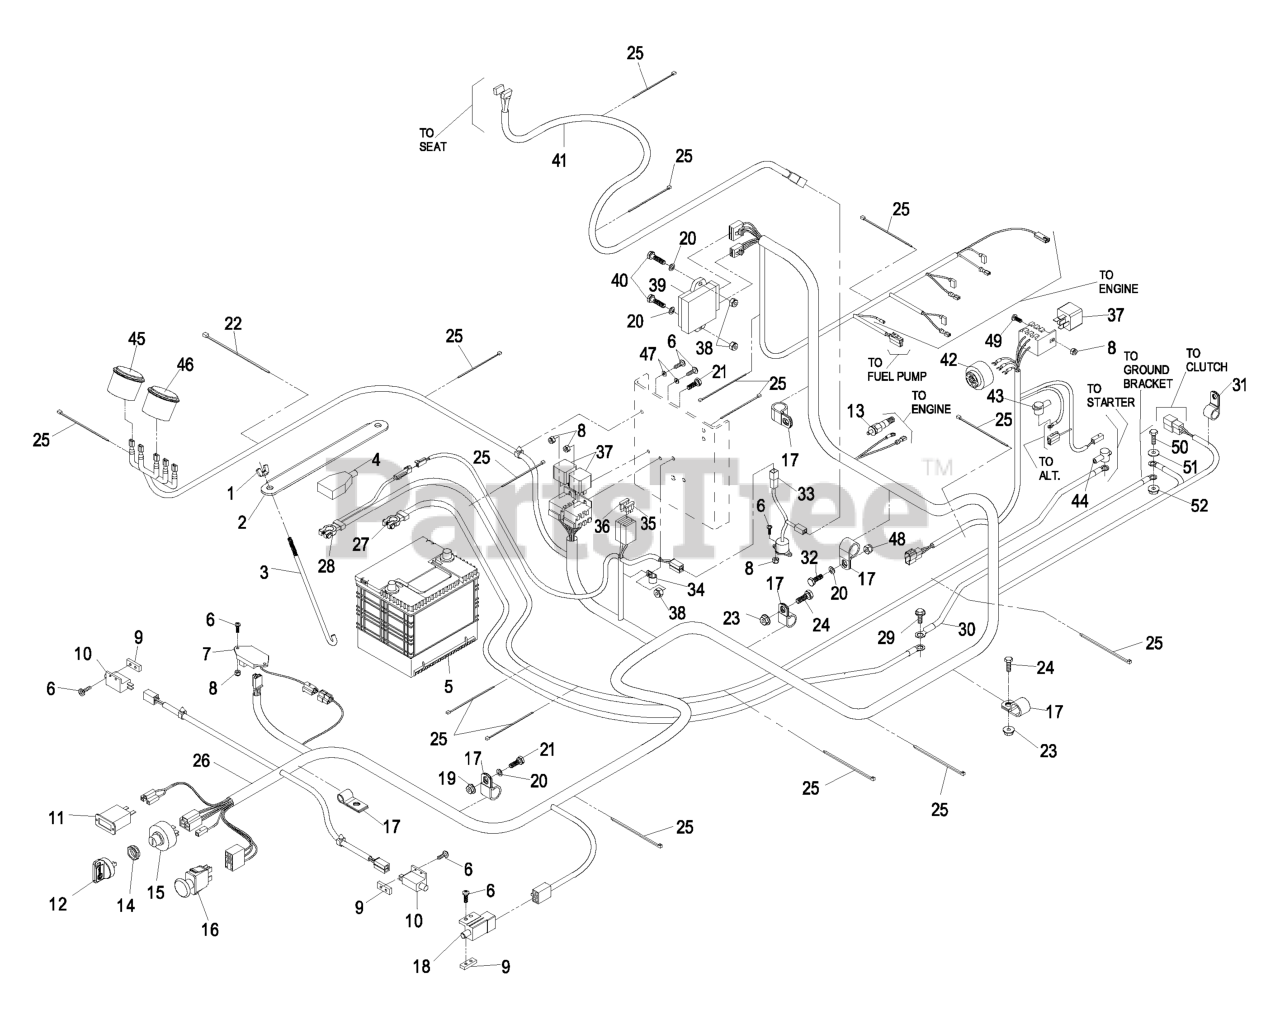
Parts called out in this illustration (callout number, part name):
1	WINGNUT
2	HOLDDOWN-BATTERY
3	BOLT-HOLDDOWN
4	INSULATOR-TERMINAL, BATTE
5	Battery, 12v SAE Post
6	SCREW-PPH
7	MODULE-DELAY, SEAT
8	NUT-LOCK, NI
9	PLATE-TAPPED
10	SWITCH-OPEN, NORMALLY
11	METER-HOUR
12	KEY-IGNITION
13	SENDER-TEMPERATURE
14	NUT-SWITCH, IGNITION
17	CLIP-LOOM
20	WASHER-FLAT
21	SCREW-HH
22	TIE-PLASTIC
24	SCREW-HH
25	TIE-PLASTIC
26	HARNESS,WIRE LXP 31DG
27	CABLE-BATTERY NEGATIVE
28	CABLE-STARTER
29	Screw-HWH 5/16-18 X 3/4 Tf
30	CABLE-ENGINE NEGATIVE
31	CLIP-LOOM
32	SCREW-HH
34	CLIP-LOOM
35	FUSE-40 AMP
36	FUSE-BLADE TYPE, 20 AMP
38	NUT-LOCK, NI
40	SCREW-HH
41	HARNESS-WIRING, SEAT
42	ALARM-TONE, DUAL
43	CAP-INSULATOR, RED
44	INSULATOR-STARTER
45	GAUGE-VOLTMETER
46	GAUGE-TEMPERATURE
47	WASHER-FLAT
48	NUT-LOCK
50	SCREW-HH
51	WASHER-FLAT
52	NUT-HHF, WHIZ
